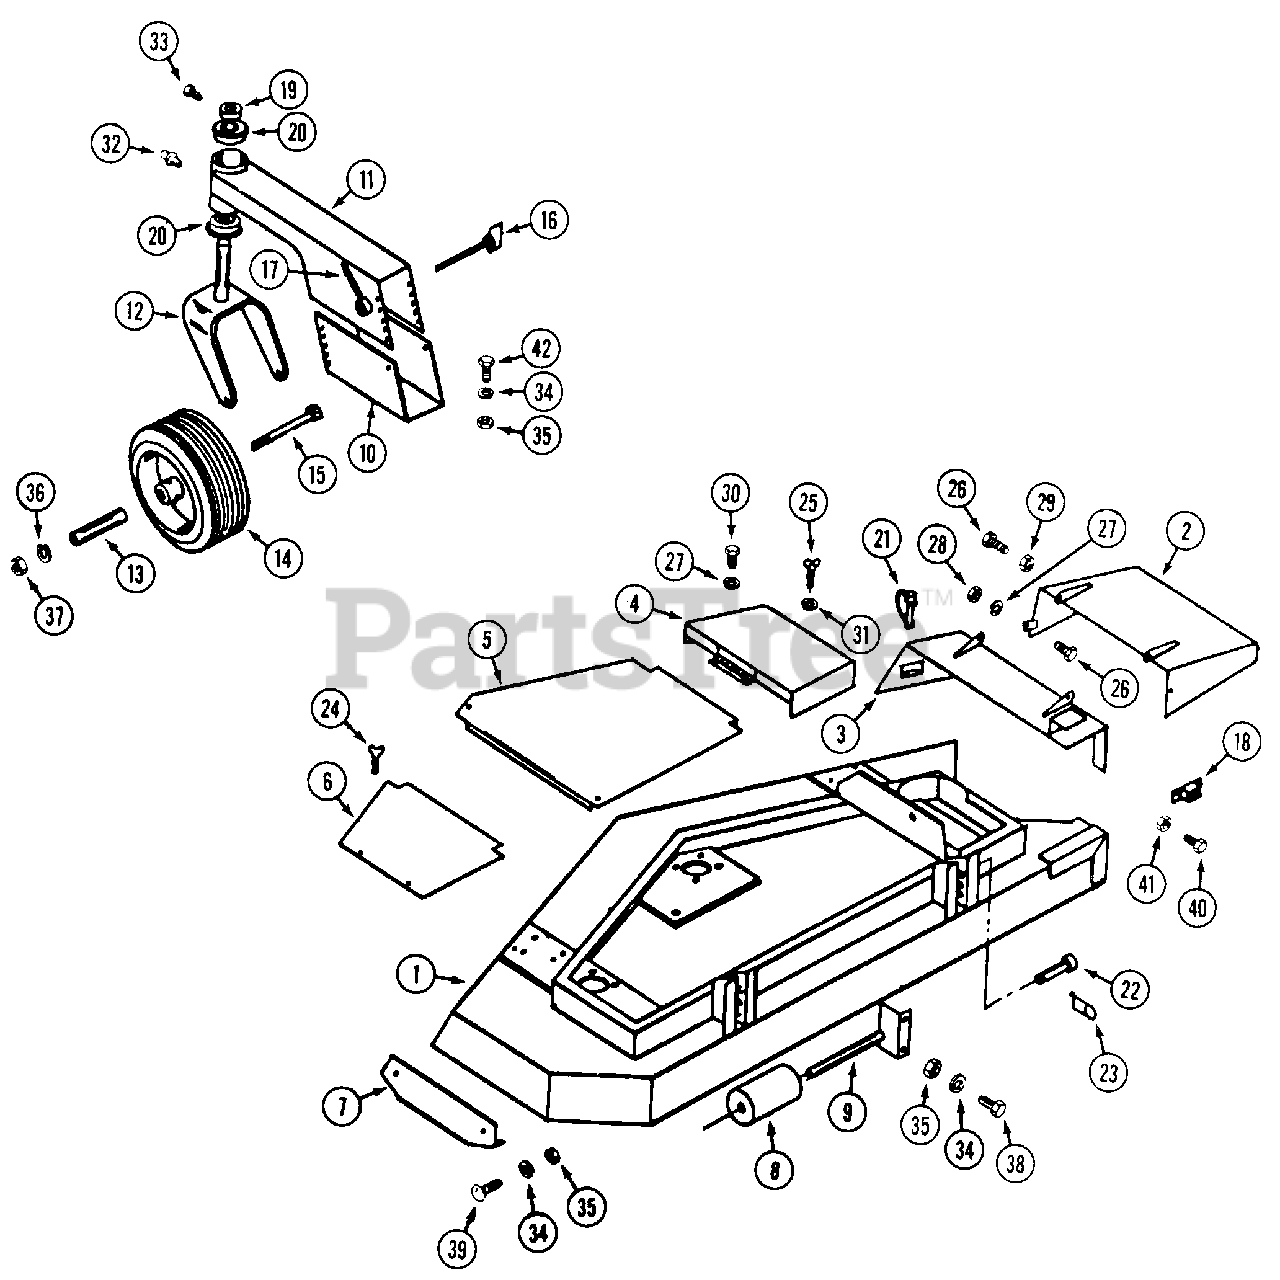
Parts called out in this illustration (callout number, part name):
2	CHUTE - foot guard
3	MOUNT - foot guard
4	COVER - pulley
5	COVER - center
8	ROLLER - anti-scalp
9	SHAFT - roller
10	BRACKET - gauge wheel mount
11	MOUNT - gauge wheel
13	AXLE - wheel
15	BOLT - 1/2"-13 x 6-1/2"
17	NUT - gauge wheel handle
18	BREAKER - circuit, 10 amp
21	PIN - "fas-tatch"
23	PIN - cotter, hair
26	BOLT - 1/4"-20 x 3/4"
27	LOCKWASHER - 1/4"
28	NUT - 1/4"-20
29	NUT - 1/4"-20 lock
30	BOLT - 1/4"-20 x 1"
31	WASHER - 1/4"
32	FITTING - grease
33	SCREW - set 5/16"-18 x 1/2" square head
34	LOCKWASHER - 5/16"
35	NUT - 5/16"-18
36	LOCKWASHER - 1/2"
37	NUT - 1/2"-13
38	BOLT - 5/16"-18 x 3/4"
39	BOLT - 5/16"-18 x 3/4" carriage
40	SCREW - #10-32 x 1/2"
42	BOLT - 5/16"-18 x 1" carriage
